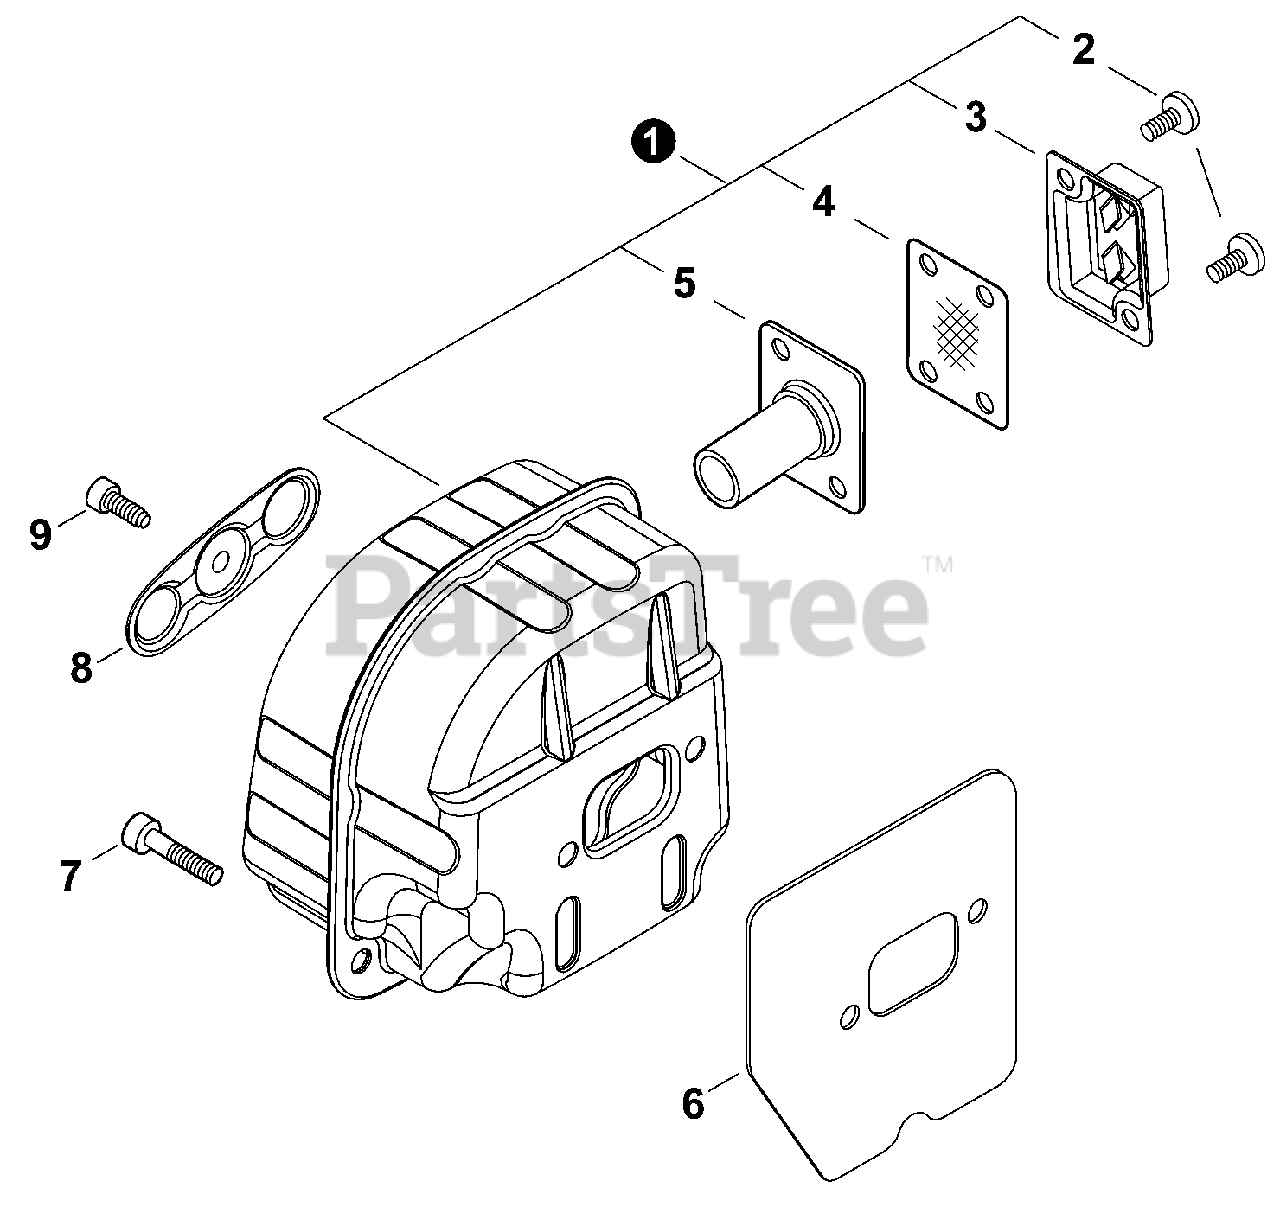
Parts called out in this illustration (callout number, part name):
1	MUFFLER ASSY
2	SCREW M4×6
3	OUTLET, EXHAUST
4	SCREEN, SPARK ARRESTER
5	GUIDE, EXHAUST
6	GASKET, EXHAUST
7	BOLT M5×18
8	PLATE, MUFFLER
9	BOLT 4×6
